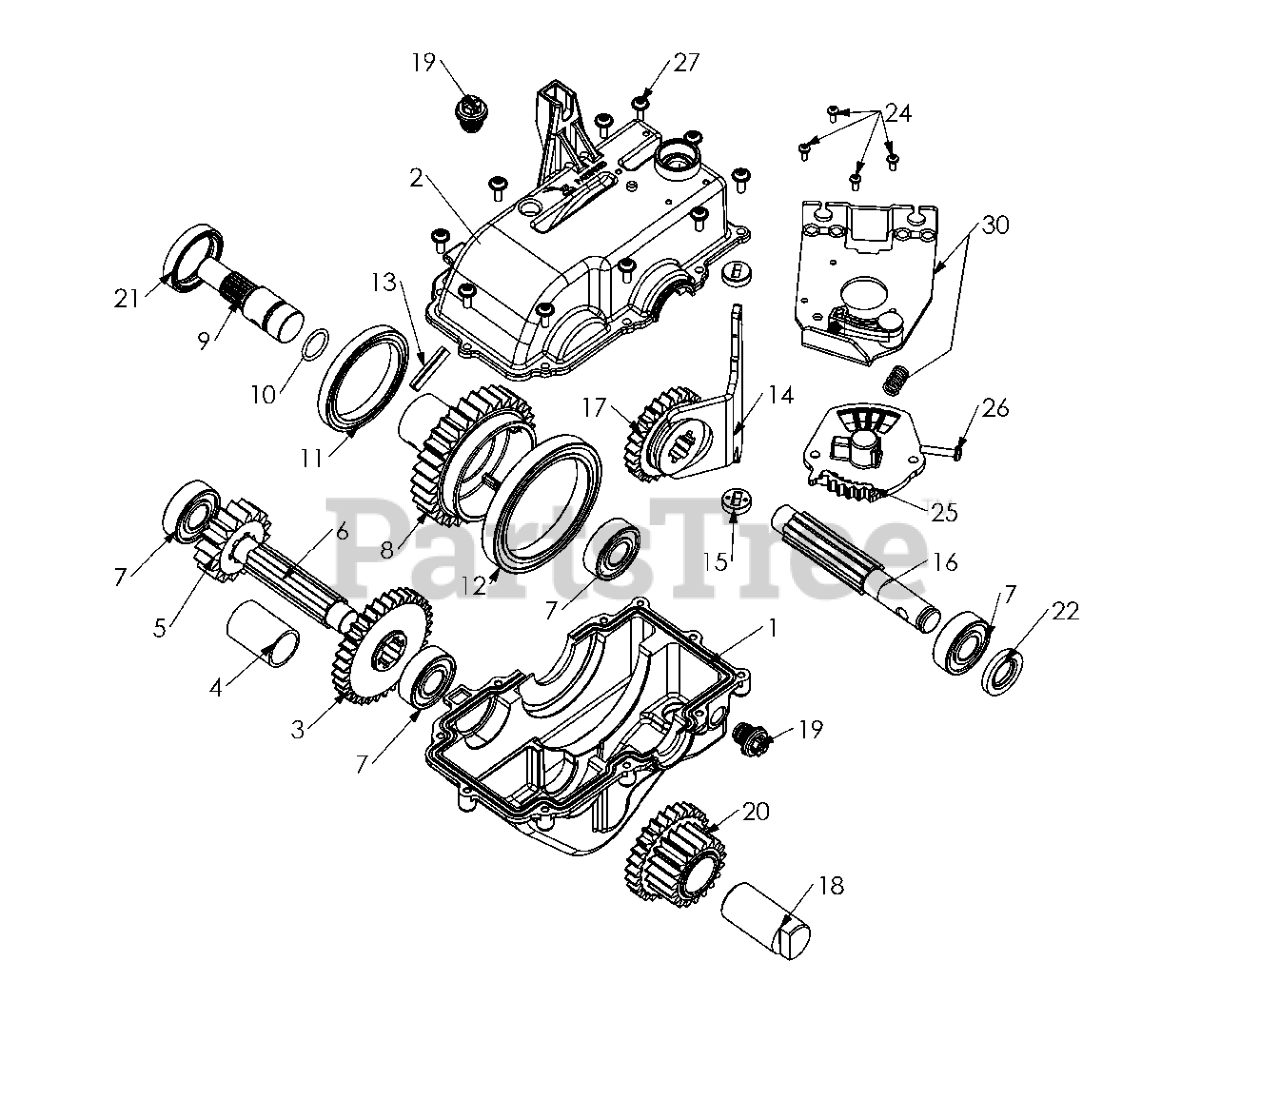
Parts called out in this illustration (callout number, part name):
4	SPACER
7	BALL BEARING
10	O-RING
11	BALL BEARING 6810
12	BALL BEARING 6813
21	WASHER
22	WASHER
24	SCREW
